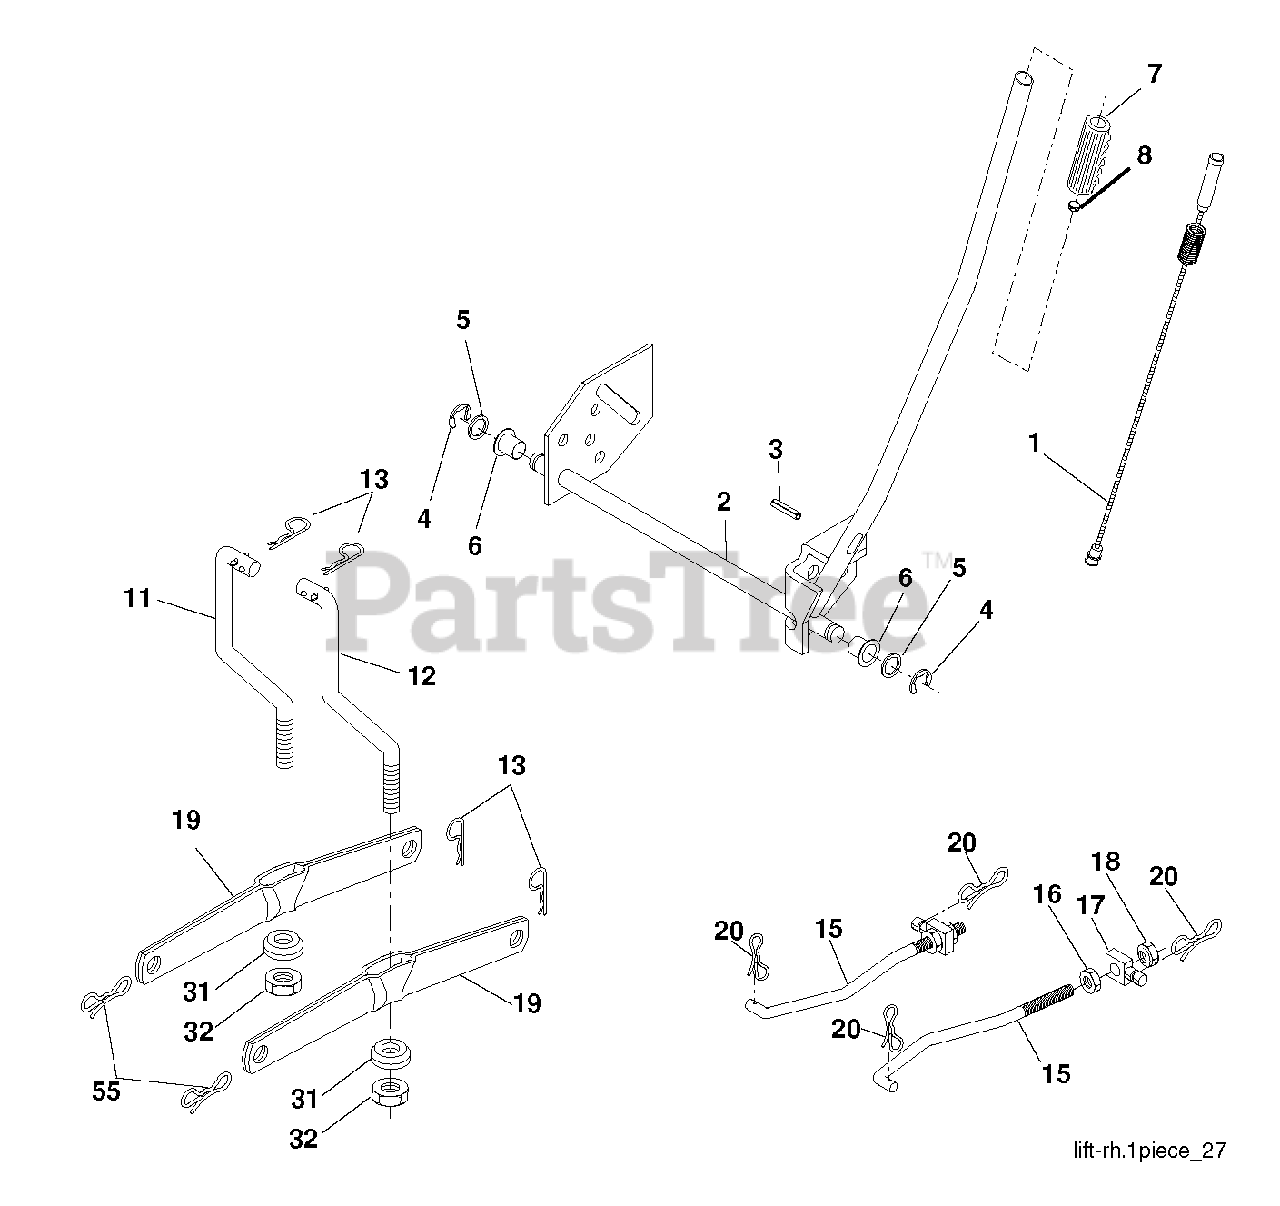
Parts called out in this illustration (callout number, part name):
1	PLUNGER.ASM.LIFT.LVR.BLK.17.32
2	SHAFT ASM R HANDLE
3	PIN GROOVE.
4	RETAINING RING LT
6	BEARING.NYLON
8	PLUNGER BUT KIT
11	LINK LIFT LH
12	LINK LIFT RH
13	Retainer Spring
15	LINK.SUSPENSION.FRONT
16	NUT.HEX.JAM.1/2-13
18	NUT.LK.W/WSH.1/2.
19	ARM.REAR.SUSPENSION
20	PIN.COTTER.7/16.BOW TI.
31	BEARING.PIVOT.LIFT
32	NUT CROWNLOCK 3/8-24
55	PIN.COTTER.5/16.BOW TI
